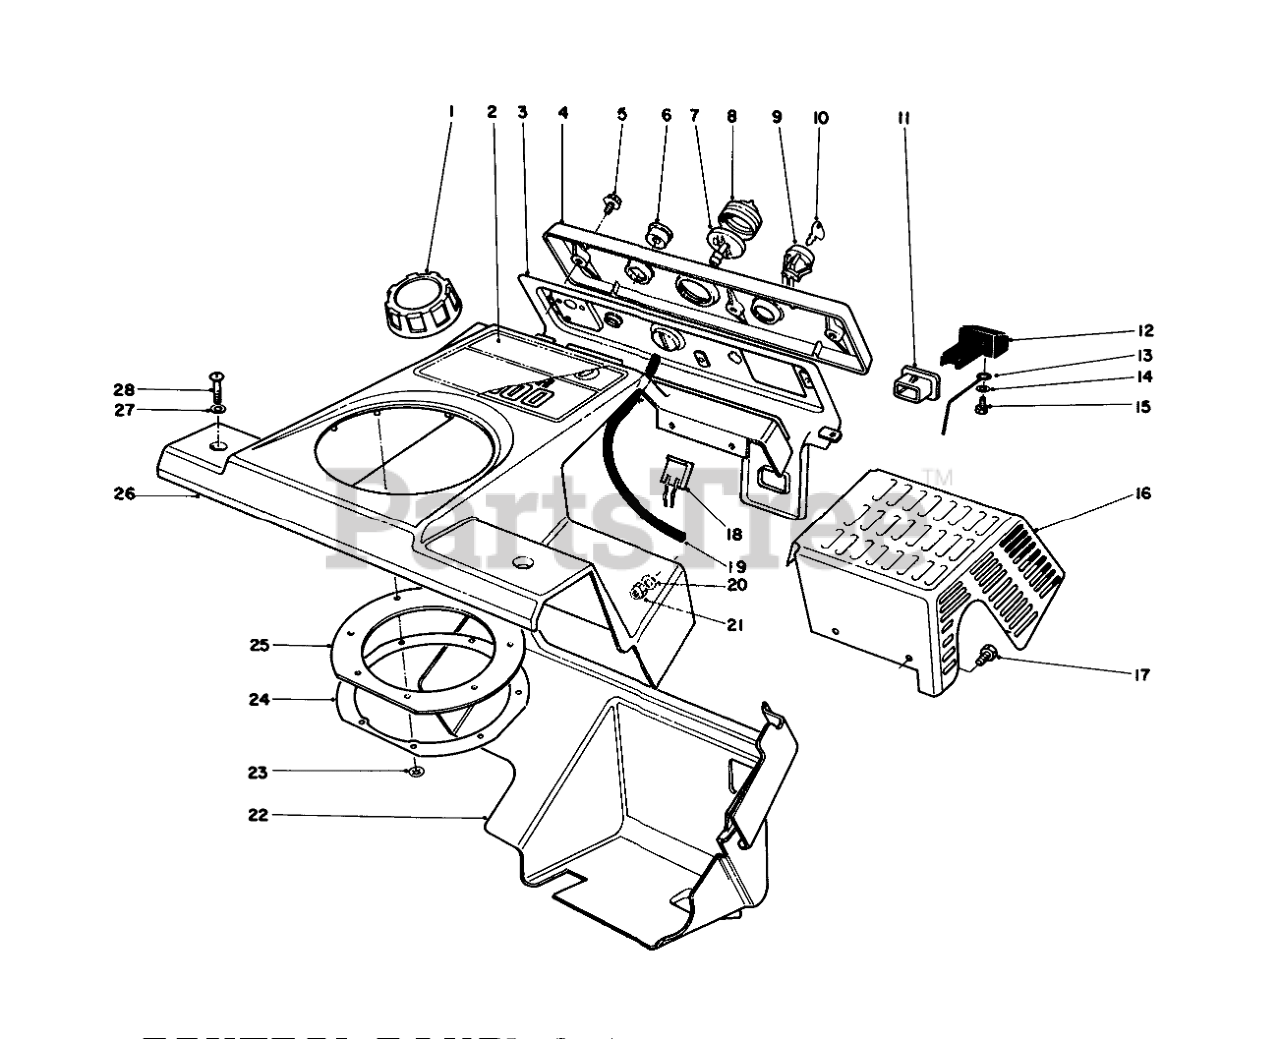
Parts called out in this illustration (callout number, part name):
1	CAP-FUEL ASM
2	Decal-CCR-2000
3	Control Panel Assembly (Incl. Ref. #68 & 11)
4	CONTROL NAMEPLATE
5	SCREW
6	GUIDE-ROPE, STARTER
7	BODY-PRIMER
8	Bulb Primer
9	SWITCH
10	Key
11	FITTING
12	CONTROL-CHOKE
13	Linkage-Choke
14	Washer
15	#8 X .625" PHILPS PAN H
16	Wa-Shield
17	SCREW-SHH
18	CONNECTOR-BODY
19	PRIMER HOSE
20	WASHER
21	NUT-LOCK, FLANGE
22	Shroud-Lower
23	Pushnut
24	Retainer-Chute Seal
25	SEAL-CHUTE
26	Upper Shroud Assembly (Incl. Ref. #2 & 23-25)
27	WASHER-FLAT
28	SCREW-PPH
